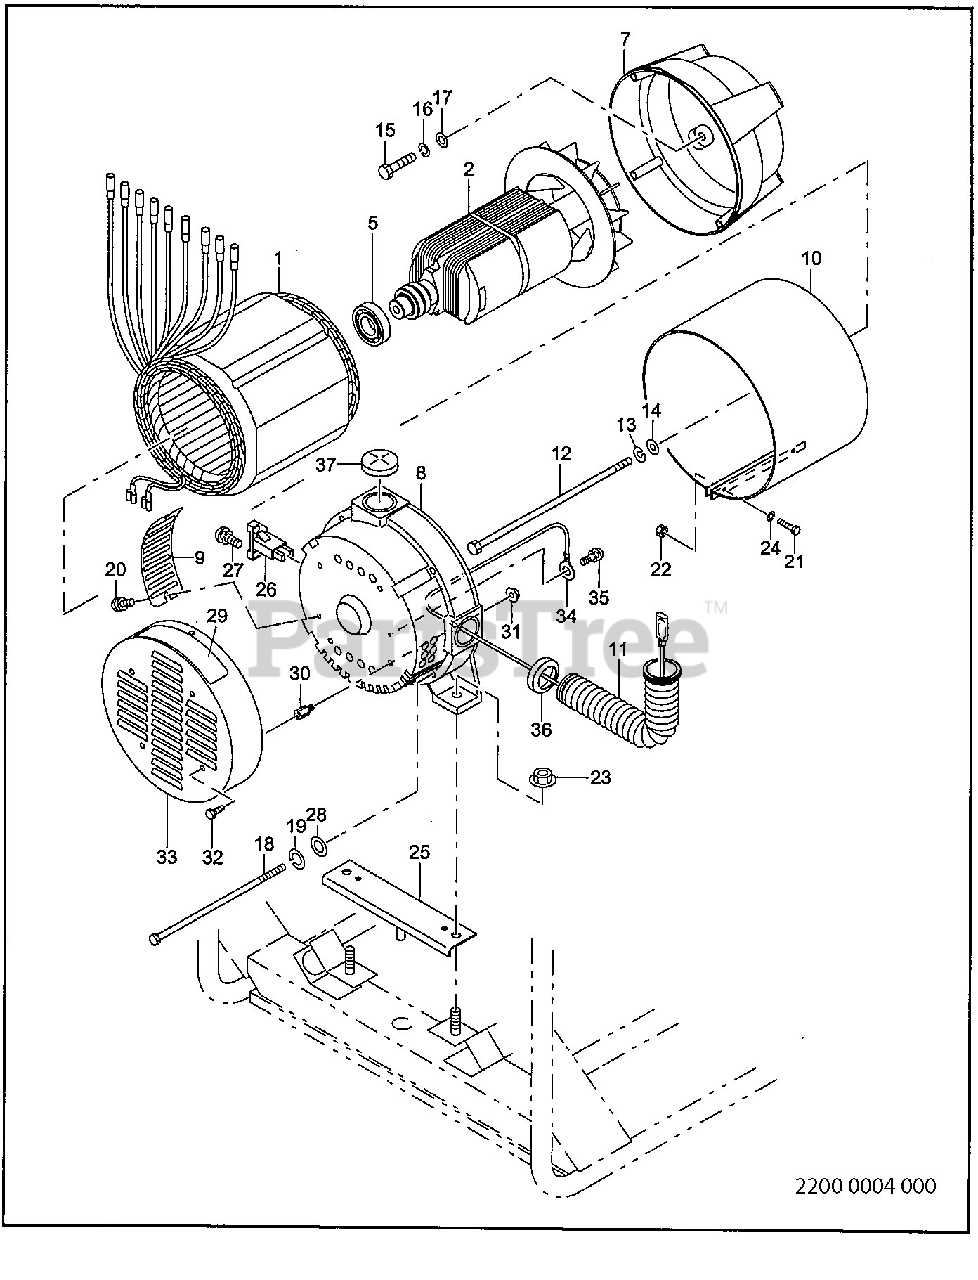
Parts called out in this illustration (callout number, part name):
1	STATOR ASSY
2	ROTOR ASSY
5	BEARING
8	REAR COVER
12	THROUGH BOLT
15	BOLT
18	COVER BOLT
20	BOLT and WASHER ASSY
21	BOLT
23	FLANGE NUT
25	GENERATOR BASE
26	BRUSH HOLDER ASSY
27	SCREW and WASHER ASSY
29	LABEL(SPEC)
31	FLANGE NUT
33	END COVER
35	SCREW and WASHER
